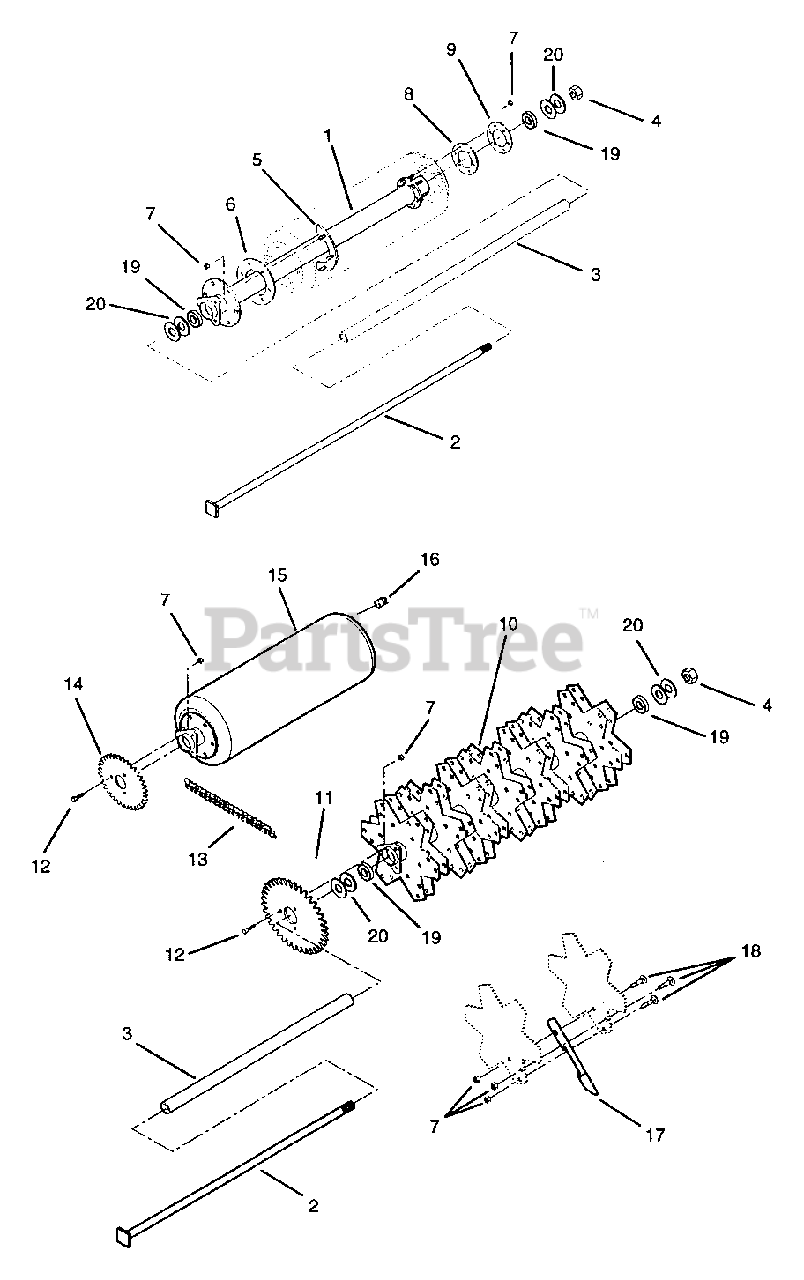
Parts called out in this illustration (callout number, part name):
1	Drum Shaft Weldment
2	Shaft Rod Weldment
3	Shaft Spacer
4	Nut-Locking-Top .62-11
5	Inner Bolt Holder Weldment
6	Large Gasket
7	Nut-Locking Unitorque .31
8	Small Gasket
9	Small Flange
10	Tang Weldment
11	Tang Sprocket
12	Bolt-Hex .31-18 x .75 Plated Grade 5
13	Chain #40
14	Drum Sprocket
15	Roller Drum
16	Test Plug-Quick Snap
17	Close Spoon Tine .75"
18	Bolt-Round Head Square Neck .31-18 x 1.50 Plated Grade 5
19	Bearing-Ball .625 x 1.375 x .44
20	Washer-Flat-Steel .630 x 1.005 x .062
